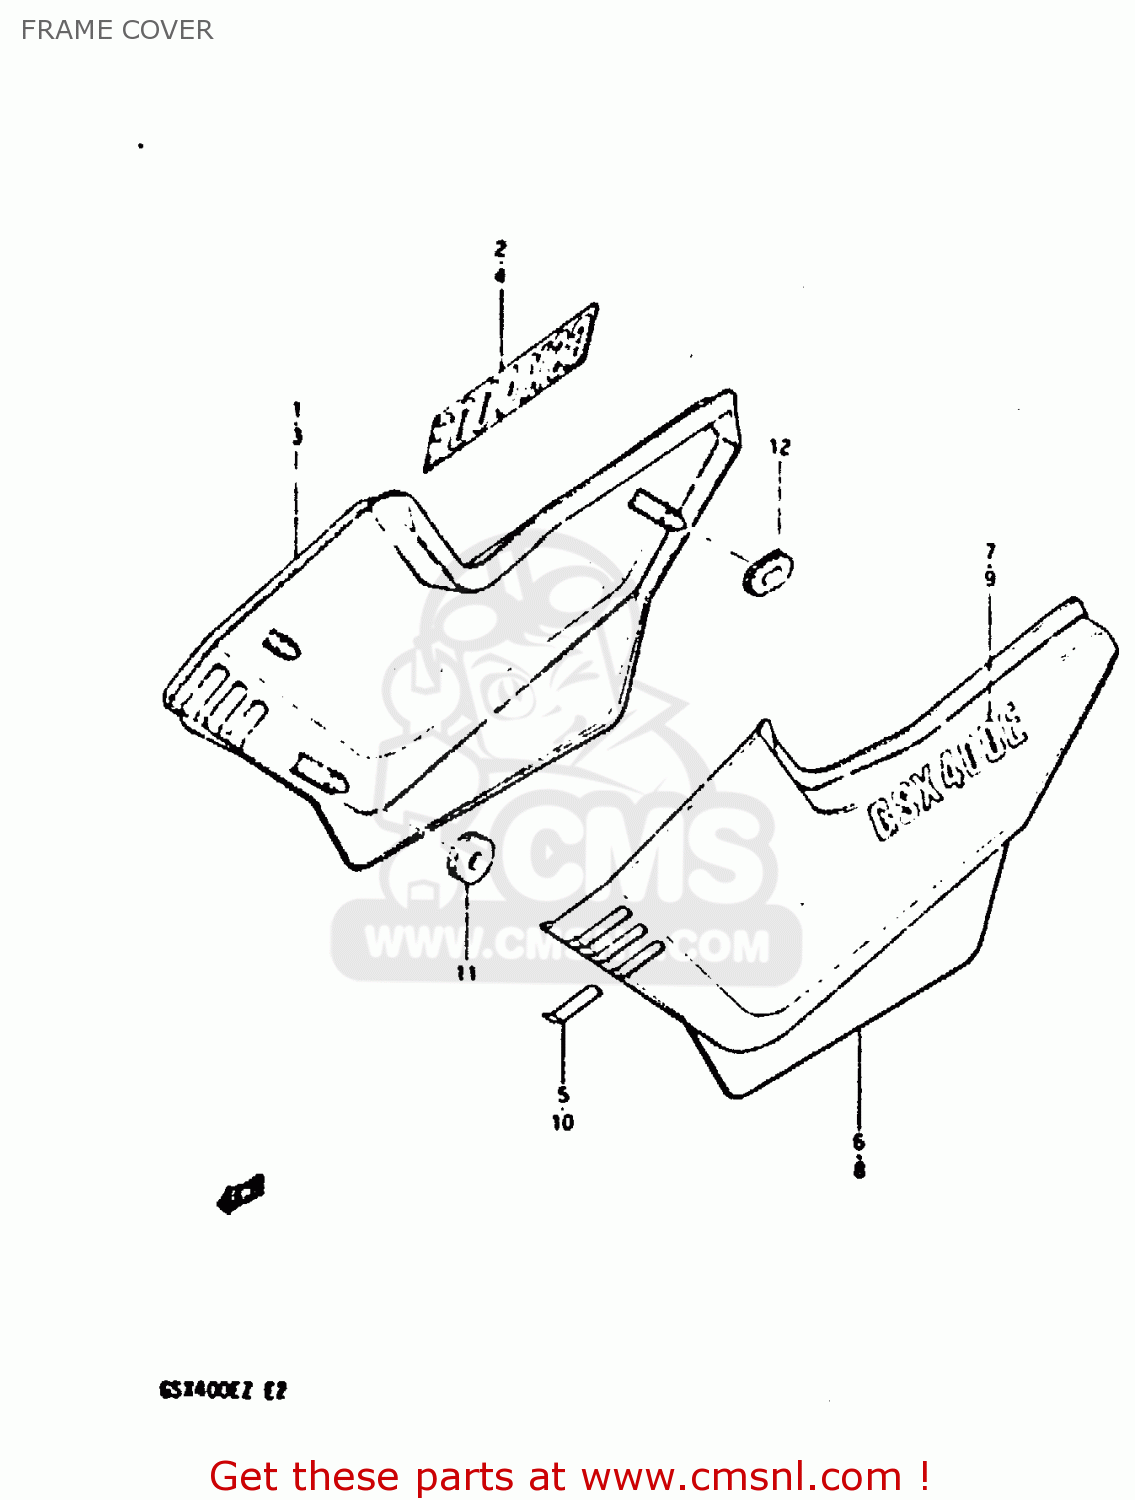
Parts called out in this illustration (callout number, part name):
1	COVER,FRAME,RIGHT
2	EMBLEM, RH
3	COVER, FRAME RH (SILVER)
4	EMBLEM, LH
5	LABEL,FRAME COVER DENT
6	COVER,FRAME,LEFT
7	EMBLEM, LH
8	COVER, FRAME LH (SILVER)
9	EMBLEM, LH
10	LABEL,FRAME COVER
11	CUSHION
12	CUSHION
